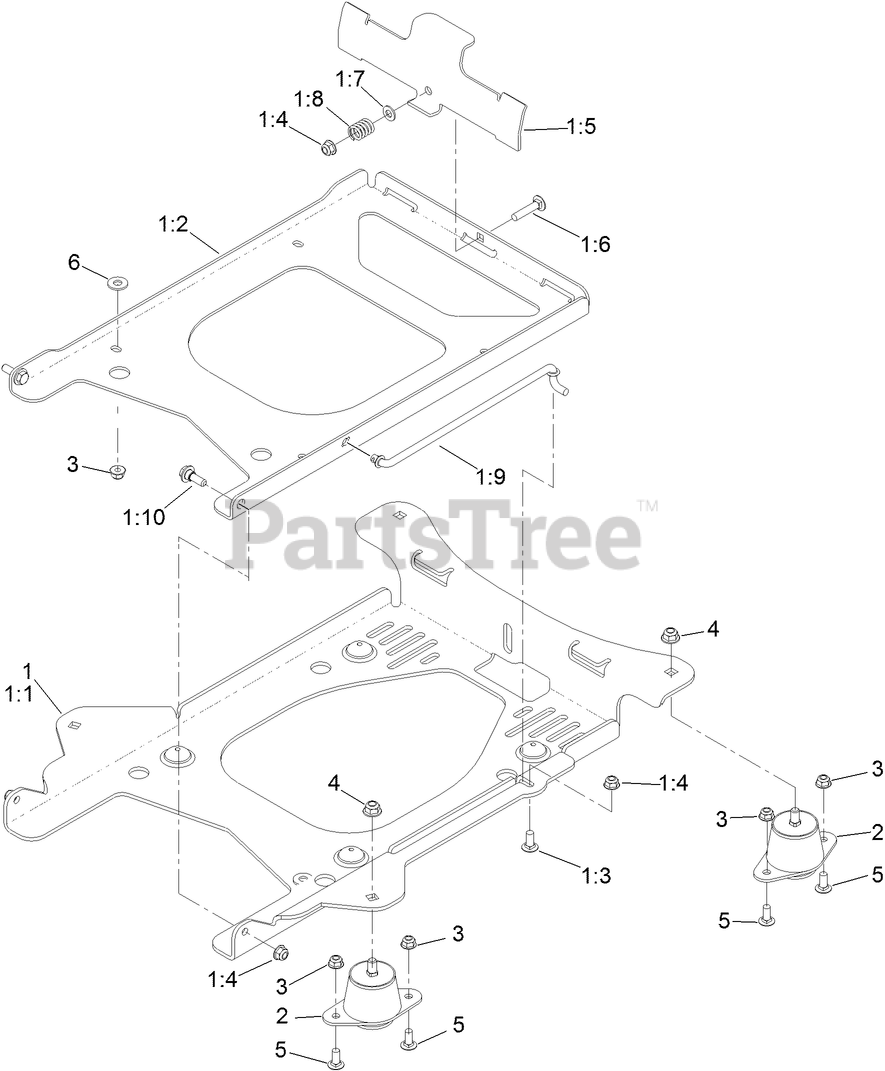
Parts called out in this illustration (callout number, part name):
1	SEAT MOUNT TILT FRAME ASM
1:1	PLATE-TILT, SEAT SUPPORT
1:2	PLATE-FRAME, SEAT
1:3	SCREW-CARR
1:4	NUT-HF, NI
1:5	PLATE-LATCH, SEAT
1:6	BOLT-CARR
1:7	WASHER-PLAIN
1:8	SPRING-COMPRESSION
1:9	ROD-PROP
1:10	SCREW-SHOULDER
2	ISOLATOR-SEAT
3	NUT-HF, NI
4	NUT-HF, NI
5	SCREW-CARR
6	WASHER-FLAT
